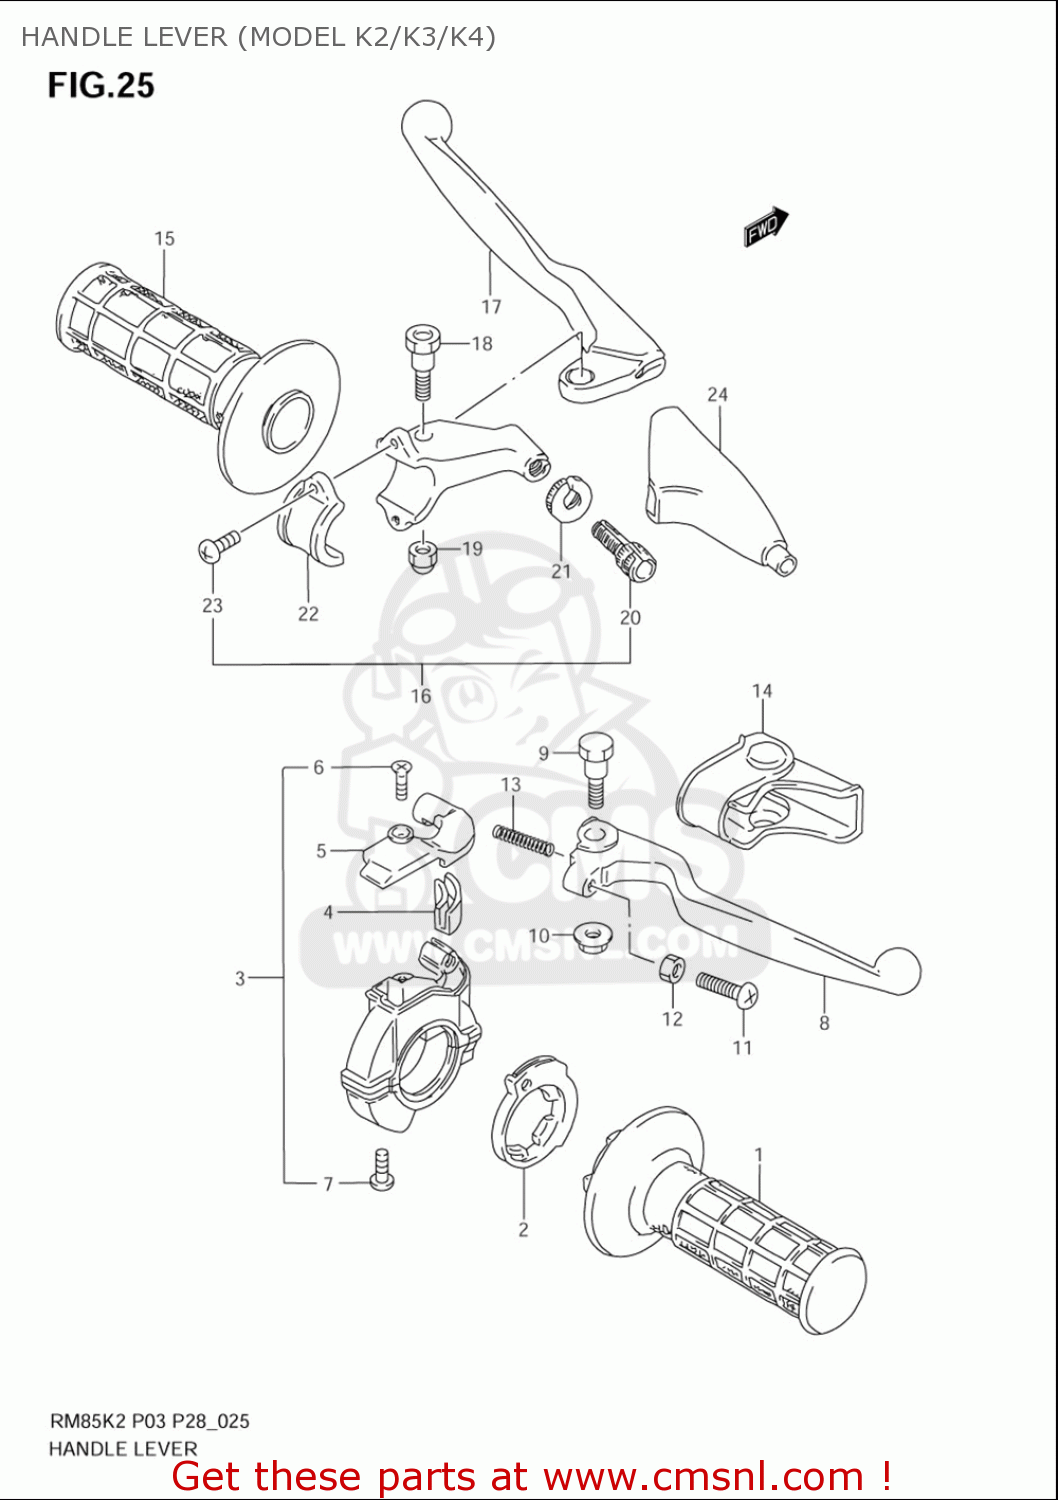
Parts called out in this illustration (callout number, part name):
1	GRIP,THROTTLE
2	ROTOR,THROTTLE GRIP
3	CASE ASSY,THROTTLE
4	GUIDE PIECE,THROTTLE
5	COVER,THROTTLE CASE
6	SCREW
7	SCREW
8	LEVER,BRAKE
9	BOLT,BRAKE LEVER
10	NUT
11	BOLT,ADJUST
12	NUT
13	SPRING,RETURN
14	COVER,BRAKE LEVER
15	GRIP,L
16	LEVER ASSY,CLUTCH
17	LEVER,CLUTCH
18	BOLT,LEVER
19	NUT 6MM
20	ADJUSTER,CABLE
21	NUT,CABLE ADJUSTER
22	BRACKET,CLUTCH LEVER HOLDER
23	SCREW(5X14)
24	COVER,CLUTCH LEVER
